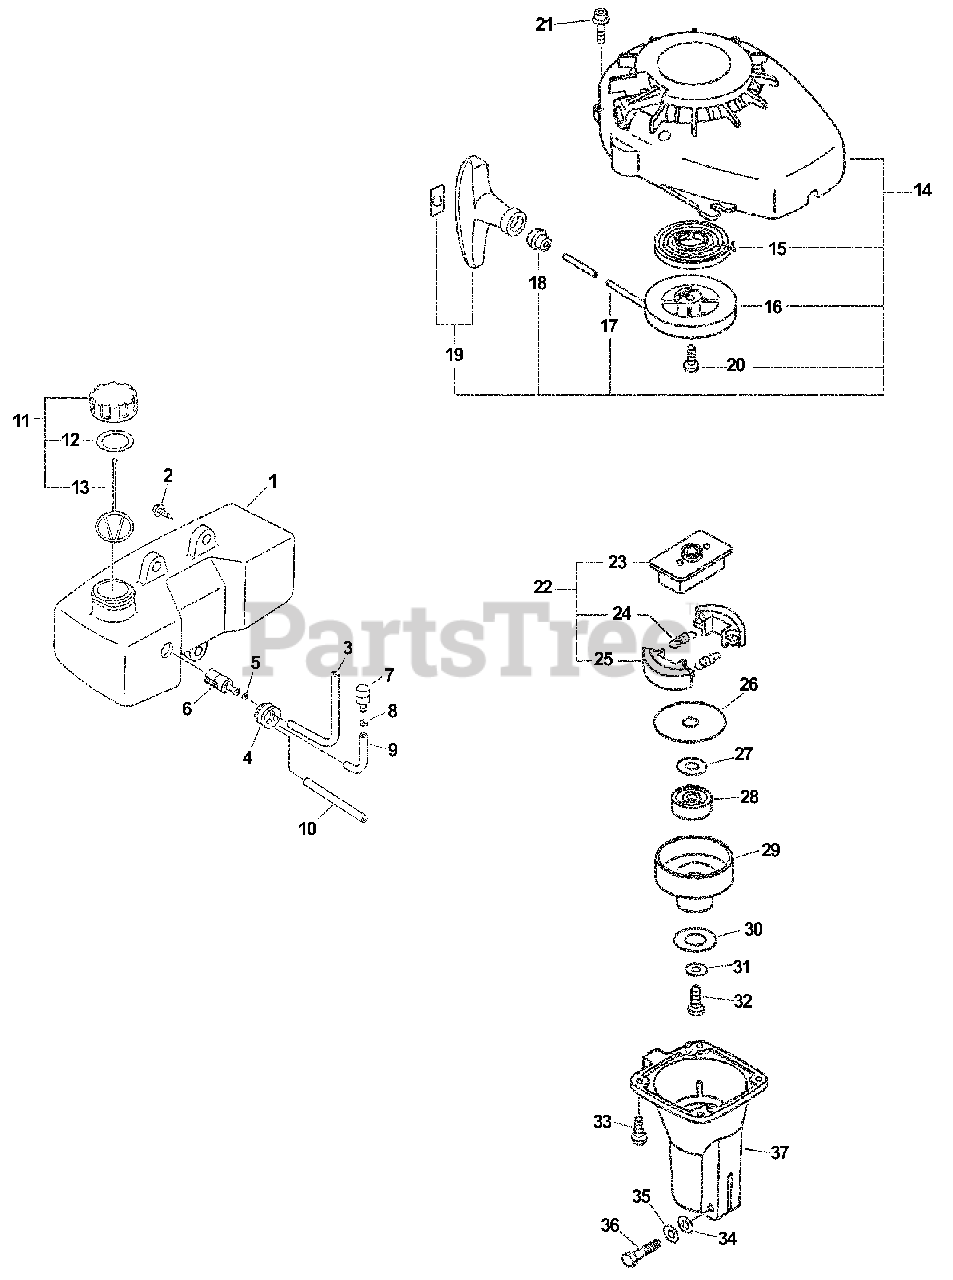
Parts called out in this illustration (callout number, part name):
1	FUEL TANK ASSY
2	SCREW - 5X15
3	PIPE - 3X5X210 -- BLACK
4	GROMMET
5	CLIP - 6
6	FILTER, FUEL
7	VENT, FUEL TANK
8	CLIP - 5.5
9	PIPE - 3X5X70 -- BLACK
10	PIPE - 3X6X50 -- CLEAR
11	CAP ASSY
12	GASKET, CAP
13	CONNECTOR, CAP
14	STARTER ASSY
15	SPRING, REWIND
16	REEL, ROPE
17	ROPE, STARTER - 3X890
18	GUIDE, ROPE
19	GRIP, STARTER
21	SCREW - 4X16
22	CLUTCH ASSY
23	HUB, CLUTCH
24	SPRING, CLUTCH
25	SHOE, CLUTCH
26	PLATE, CLUTCH
27	WASHER - 10
28	BEARING, BALL - 6000
29	DRUM, CLUTCH
30	WASHER, CLUTCH
31	WASHER, CLUTCH
32	SCREW - 6X12
33	SCREW - 4X14
34	WASHER - 5
35	LOCKWASHER - 5
36	BOLT - 5X25
37	CASE, CLUTCH
